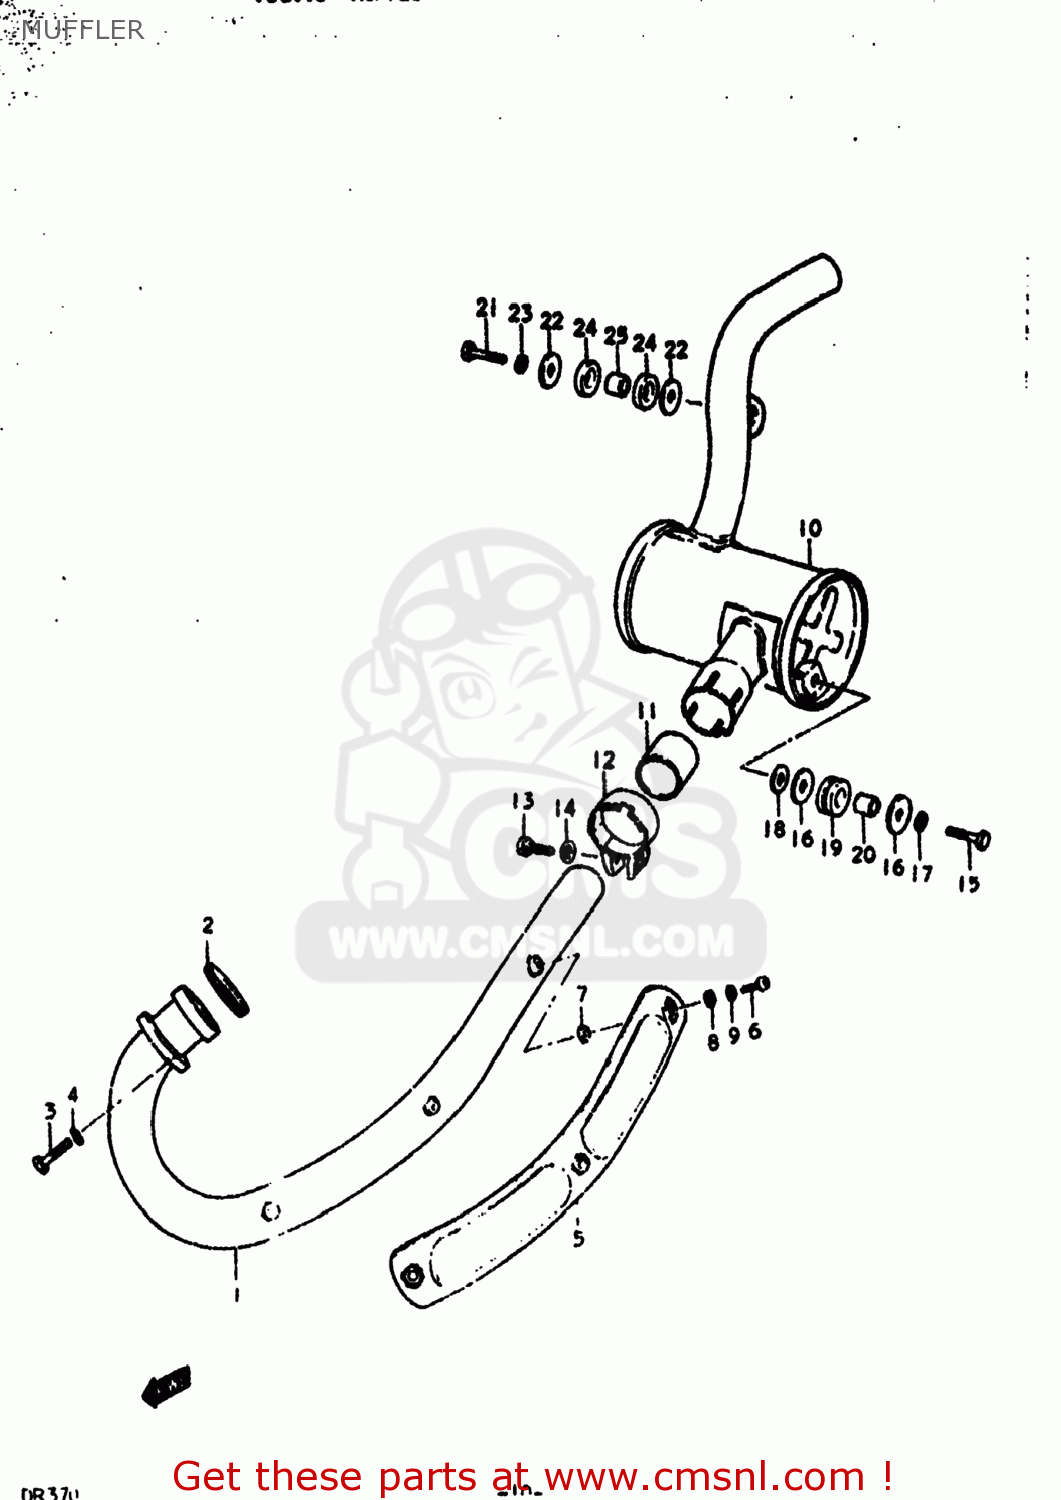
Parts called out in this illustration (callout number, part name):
1	PIPE,EXHAUST
2	GASKET,EXHAUST PIPE (NAS)
3	BOLT (8X30)
4	LOCK WASHER
5	COVER,EXHAUST PIPE
6	SCREW
7	GASKET 6.2X12X1.5 (MCA)
8	WASHER
9	LOCK WASHER
10	BODY,MUFFLER
11	CONNECTOR,MUFFLER
12	CLAMP,MUFFLER CONNECTOR
13	BOLT 8X35
14	WASHER
15	BOLT (8X30)
16	WASHER (8.5X29X1.6)
17	LOCK WASHER
18	GASKET
19	CUSHION
20	SPACER (8.6X13.8X13)
21	BOLT(8X27)
22	WASHER (8.5X29X1.6)
23	LOCK WASHER
24	CUSHION
25	SPACER (8.6X13.8X13)
